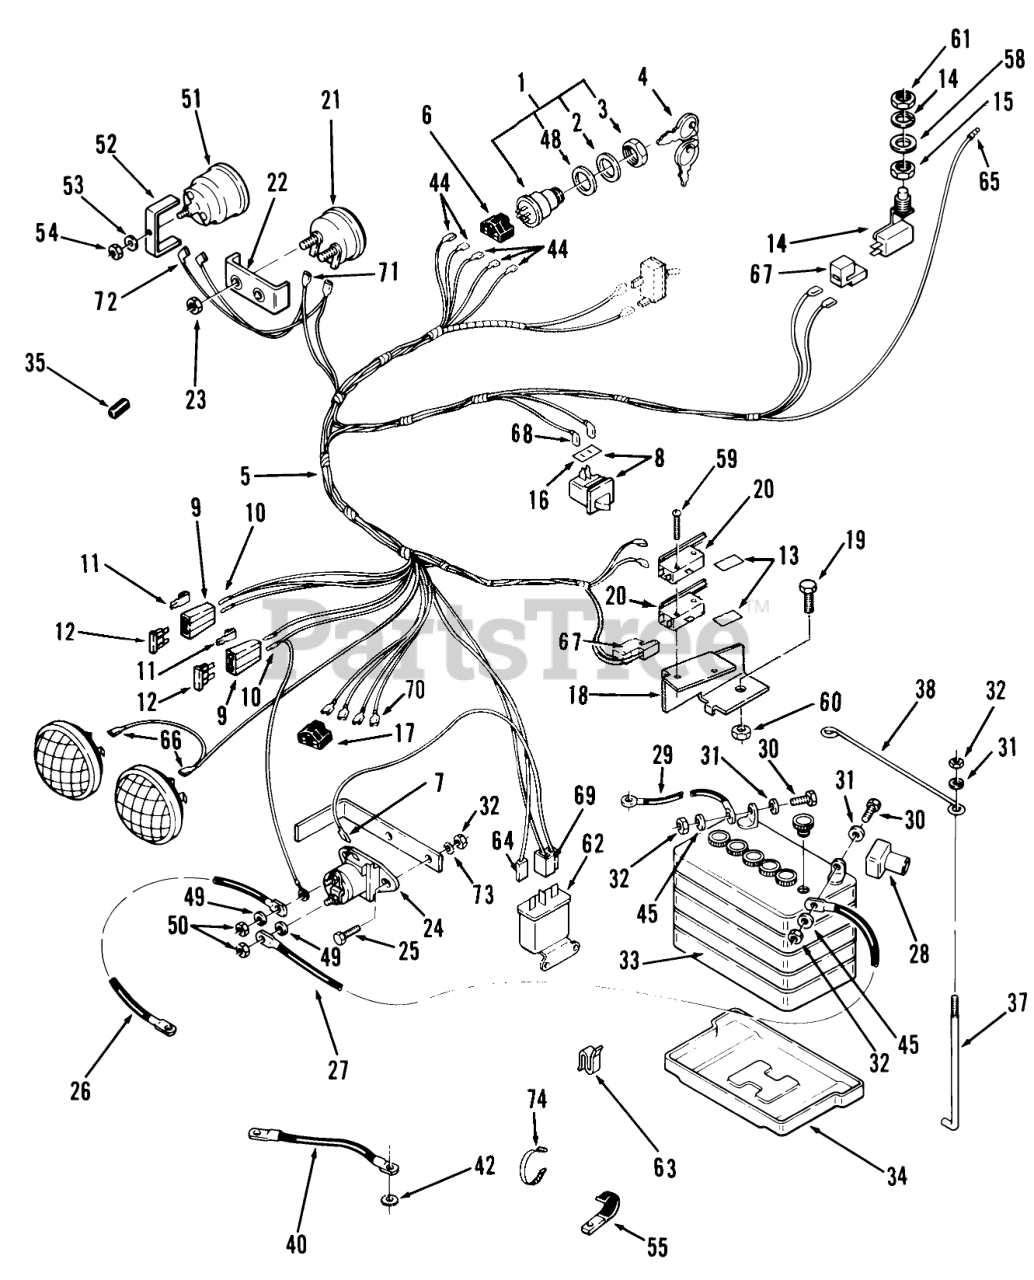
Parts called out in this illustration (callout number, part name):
1	Ignition Switch Ass-y
2	LOCKWASHER
4	KEY PADDED
4	Ignition Key
5	WIRING-HARNESS & DIA
5	Wiring Harness Assembly 420-LSE
5	WIRING HARNESS
6	CONNECTOR-5 WAY-SERV
7	TERMINAL 10
8	SWITCH ASM (SERVICE)
9	AUTO-FUSEBLOCK TERM
10	TERMINAL FUSE
12	FUSE-BLADE, 5 AMP
12	FUSE-BLADE, 15 AMP
12	FUSE-BLADE, 25 AMP
13	BARRIER - SWITCH
14	SWITCH-PUSH
15	NUT-HEX, SPECIAL
16	SHIELD-DIRT SPST
17	5-CONTACT CONN BODY
18	Support-Switch
19	Bolt
20	SWITCH
21	Voltmeter (w/109650)
22	CLAMP MOUNTING
23	HEX NUT 10-32 E.S.
24	SOLENOID-STARTER
25	Screw
26	ASSY WIRE
26	Cable-Solenoid to Starter Twin Cylinder
27	CABLE-BLACK
28	Boot
29	ASSY WIRE
30	Bolt
32	Nut
33	Battery Maintenance Free 416
33	Battery
34	TRAY BATTERY
35	GRIP
35	VALVE LEVER GRIP
38	ROD HOLD DOWN B
40	WIRE GROUND
42	Washer-Lock
44	Terminal
45	Washer
48	Washer
49	Washer
50	Nut
51	Hourmeter 314, 417
52	HOUR METER CLAMP
53	Lockwasher
54	Hex Nut
55	CLIP
58	SPACER SWITCH
59	Screw
60	NUT HEX 4-40 ELAST
61	NUT-HEX SPECIAL
62	Relay
63	CLIP-CABLE
64	TERMINAL 10
65	Sur-Plug
67	CONNECTOR BODY
68	Terminal
69	CONNECTOR BODY B
70	Connector Part of 5
71	TERMINAL-TAB RCPT
72	Terminal Part of 5
73	LOCKWASHER
74	PLASTIC TIE
